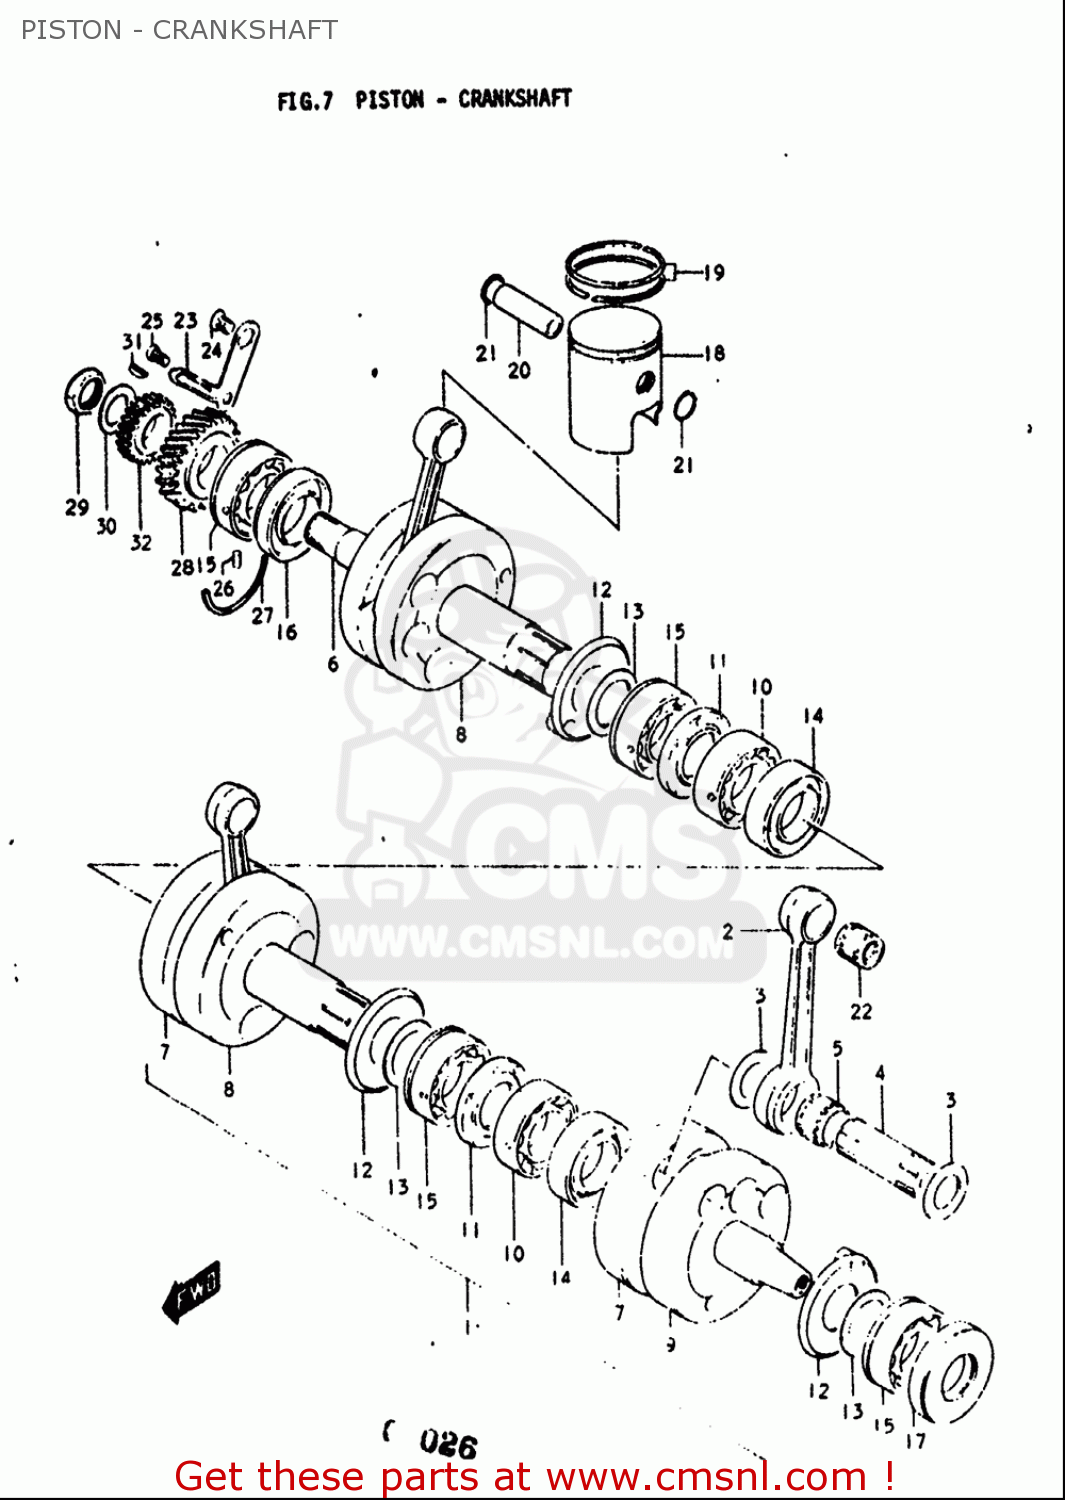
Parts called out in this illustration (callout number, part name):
2	CONNECTING ROD
3	WASHER
5	BEARING(20X26X16.7)
10	BEARING(25X52X15)
12	PLATE,CSHAFT OIL GUIDE
13	SHIM(25X36X0.5)
14	SEAL,OIL(25X52X11)
15	BEARING 25X52X15
16	SEAL,OIL(32X52X8.4)
17	SEAL,OIL(25X52X8.5)
18	PISTON SET(OS:0.5)
19	RING SET,PISTON
20	PIN,PISTON 14MM
21	RING,SNAP 14MM
22	BEARING(14X18X19.8)
24	SCREW
25	SCREW
26	PIN
27	C RING
29	NUT
30	WASHER
31	KEY
